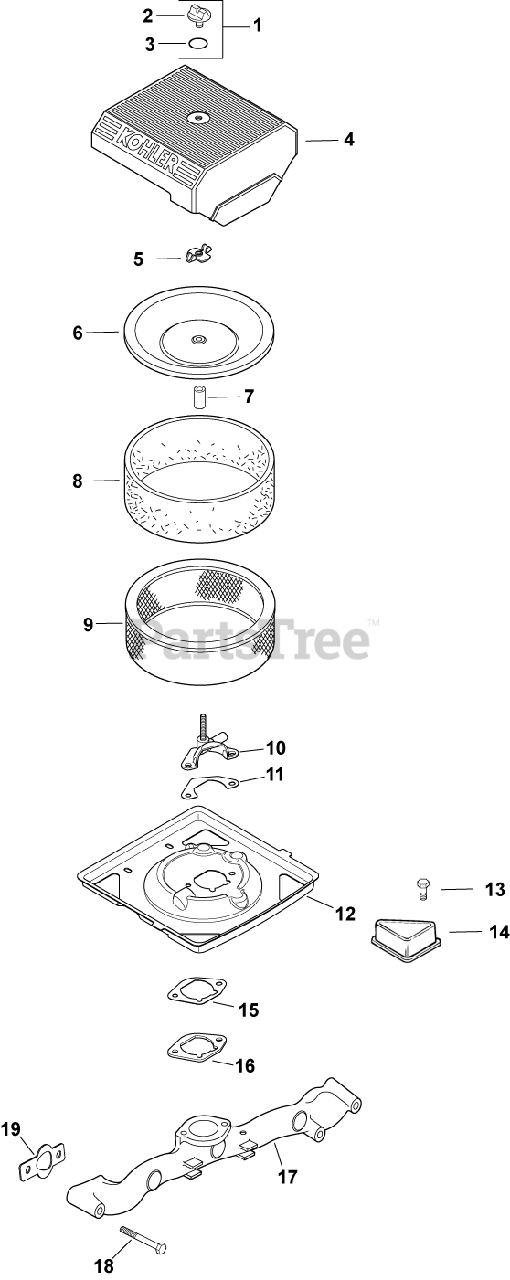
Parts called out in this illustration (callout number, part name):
1	KIT, KNOB W/SEAL
2	KNOB, COVER
4	COVER, AIR CLEANER
5	NUT, WING
6	COVER, INNER AIR CLEANER
7	SEAL, INNER AIR CLEANER
8	ELEMENT, PRECLEANER (LOW)
9	ELEMENT, AIR CLEANER - Also available Retail Packaged 47 883 03-S1 Air Filter Kit
10	CUP, FUEL SPITBACK W/NIPPLE
11	GASKET, FUEL SPITBACK CUP
12	BASE, AIR CLEANER-USE 24 094 86-S
13	SCREW, WSH HD TAP #8-18X1/2"
14	COVER, BLOWER HOUSING USE 24 096 160-S
15	GASKET, AIR CLEANER BASE
16	SPACER, AIR CLEANER BASE
17	MANIFOLD, INTAKE
18	SCREW, FLG M6X1.0X55
19	GASKET, INTAKE MANIFOLD USE 24 041 79-S
